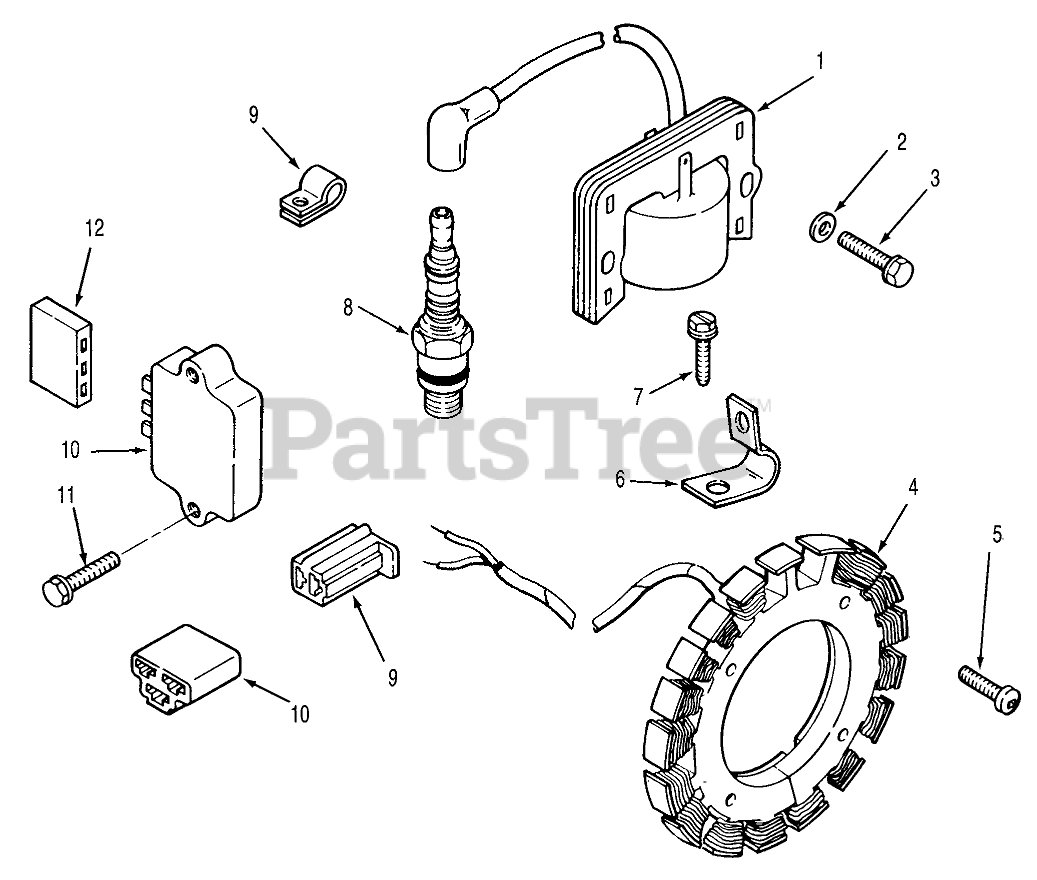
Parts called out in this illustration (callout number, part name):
1	Module-Ignition
2	Washer
3	Screw
4	Stator Kit 15 amp (Includes Item# 8)
5	Screw
6	Clip
7	Hex. Washer Hd. Screw No. 8-32 x 3/8
8	Plug-Spark
9	Clip-Cable
10	Regulator-Rectifier
11	Screw
12	Connector
